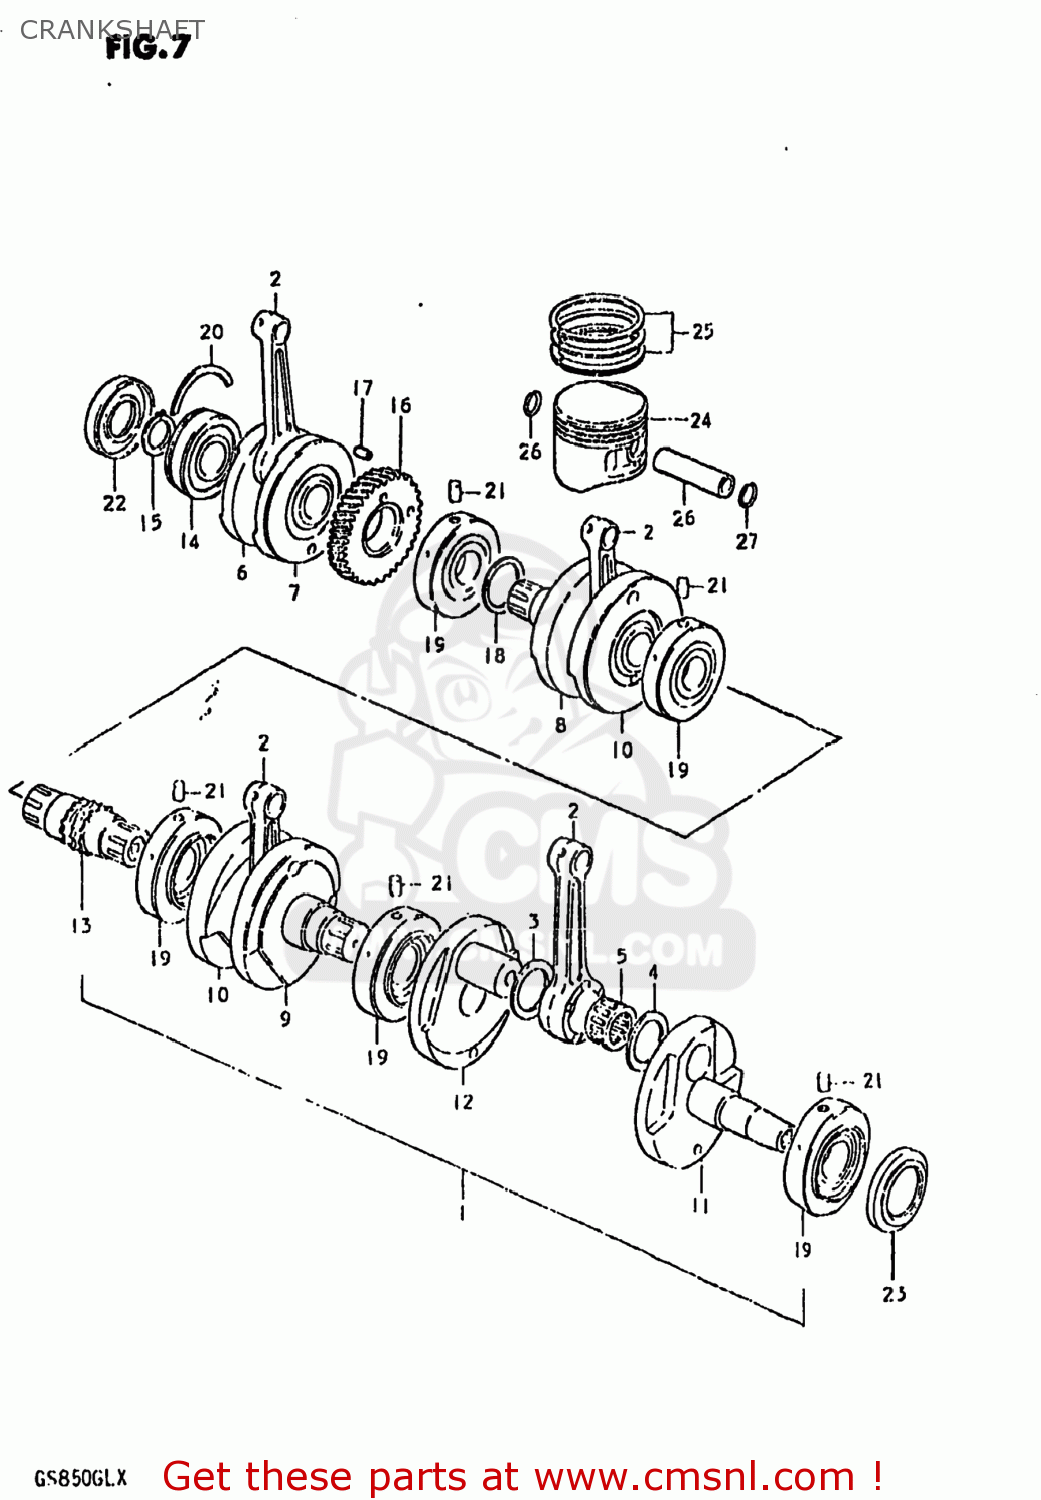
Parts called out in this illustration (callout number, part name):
1	CRANKSHAFT ASSEMBLY
2	CONNECTING ROD
3	WASHER (29X48X2)
4	WASHER (29X48X1)
5	BEARING(29X39X20)
6	CRANKSHAFT
7	WEB,CRANK,RIGHT
8	CRANKSHAFT
9	CRANKSHAFT, MIDDLE LH
10	WEB,CRANK,MIDDLE
11	CRANKSHAFT,LEFT
12	WEB,CRANK,LEFT
13	SHAFT,TIMING CHAIN DRIVE
14	BEARING(30X72X19)
15	CIRCLIP,30MM
16	GEAR,PRIMARY DRIVE
17	PIN
18	WASHER
19	BEARING
20	C RING
21	PIN
22	SEAL,OIL(30X72X11)
23	OIL SEAL
24	PISTON
25	RING SET,PISTON
26	PIN,PISTON
27	CIRCLIP
